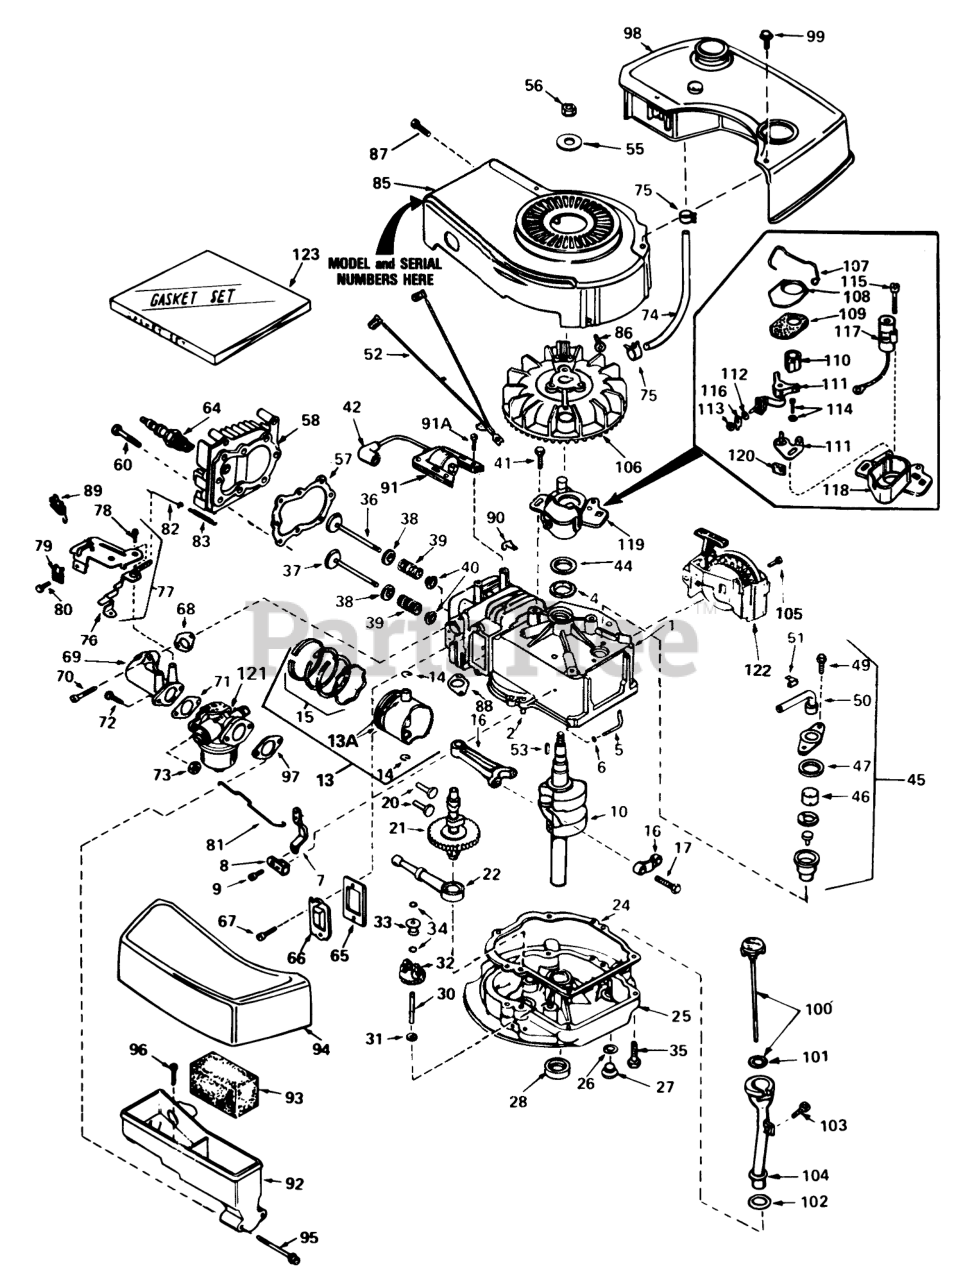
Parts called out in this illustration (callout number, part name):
1	Cylinder Assy. (Incl. Ref. #2, 4 & 105)
2	Pin-Dowel
4	Seal-Oil
5	Rod, Governor (Incl. Ref. #6)
6	Washer-Flat
7	Governor Lever
8	Clamp-Lever, Governor
9	Screw
10	Crankshaft
13	Piston, Pin & Ring Assy. (Std.)(Incl. Ref. #13A, 14 & 15)
13	Piston, Pin & Ring Assy. (.010 oversize)(Incl.Ref. #13A, 14& 15)
13	Piston Pin & Ring Assy. (Incl. Ref. #14 & 15) (.020 Oversize)
13A	Piston & Pin Assy. (Std.) (Inc. #14)
13A	Piston & Pin Assy. (.010 oversize)(Incl. Ref. #14)
13A	Piston & Pin Assy. (.020 oversize)(Incl. Ref. #14)
14	Ring-Retaining, Piston Pin
15	Ring Set Piston (Std.)
15	Ring Set Piston (.010 Oversize)
15	Ring Set Piston (.020 Oversize)
16	Rod Assy., Connecting (Incl. Ref. #11)
17	Bolt-Rod, Connecting
20	Lifter-Valve
21	Camshaft(Mech.Comp. Release)
22	Oil Pump ASM
24	Gasket, Mounting
25	Flange Assy., Mounting (Incl. Ref. #26 thru 30)
26	Gasket-Oil Drain
27	Plug Oil Drain
28	Seal Oil
30	Shaft-Governor
31	Washer-Flat
32	Gear Assy., Governor (Incl. Ref . #31 )
33	Spool-Governor
34	Ring-Retaining
35	Screw (1/4-20 x 1-1/4)
36	Valve Intake (Std.)(Incl. #38, 39 & 40)
36	Valve Intake (Incl. Ref. #38 40)(1/32" Oversize)
37	Valve, Exhaust (Std.) (Incl. #7, 8 & 9)
37	Valve, Exhaust (1/32" oversize)(Incl. Ref. #38, 39 & 40)
38	Cap-Upper Valve Spring
39	Spring-Valve
40	Cap-Valve, Spring
42	Cover-Spark Plug
44	Gasket Stator
45	Breather Assy. (Incl. Ref. #46 thru 51 )
46	Element-Breather
47	Gasket-Breather
49	Screw (10-24 x 9/16)
50	Tube, Breaker
51	Clip, Breather
52	Wire Ground
53	682488 LB GRASS HI-
55	Washer-Belleville
56	Nut-Flywheel
57	63573 GIL 42 SNWTHW
58	Head-Cylinder
60	Screw (5/16-18x1-1/2)
64	Plug, Spark (J17LM or equiv.)
64	Plug, Spark (Champion RCJ-8)
65	Gasket-Breather
66	Cover-Valve
68	Gasket-Intake
69	Pipe, Intake (Incl. Ref. #68)
70	Screw (1/4-20 x 1)
71	Gasket-Carburetor
72	Screw (1/4-28 x 7/8)
73	Nut and Lock Washer (1/4-28)
74	Line-Fuel
75	Clamp-Line, Fuel
76	Lever Control
77	Control Assy., Speed (Incl. Ref. #76, 78 & 89)
78	Screw, Hex Washer Hd Shoulder Self-Tap
79	Conduit
80	Screw (10-32 x 3/8)
81	Link-Throttle
82	Link Governor Spring
83	Spring Governor
85	Housing Blower
86	Screw
87	Screw (10-24 x 9/16)
88	Gasket Exhaust
89	Terminal
90	Clip-Wire
91	Lamination
91A	Screw
92	Body Air Cleaner
93	Filer, Air
94	Cove, Air Cleaner
95	Screw Fil Hd.
96	Screw, Hex Hd.
97	Gasket-Air Cleaner
98	Tank, Fuel
99	Screw (10-32 x 35/64)
100	Dipstick, Oil (Incl. Ref. #101)(Twist Lock)
103	Screw (10-32 x 1/2)
104	Tube-Oil Fill
105	Screw (1/4-20 x 1/2)
106	FIywheel
107	Spring Breaker Box
108	Cover-Dust
109	Gasket-Dust Cover
110	Cam-Breaker
111	Breaker Assy.
114	Breaker Screw
115	Condenser Screw
116	Terminal, Ground
117	Condenser
118	Stator Plate
119	Stator Assy. (Incl. Ref. #107, 111 thru 118 & 120)
120	Felt,Cam Wiper
121	Carburetor (Incl. Ref. #71)
122	Starter, Side Mount
123	Gasket Set
